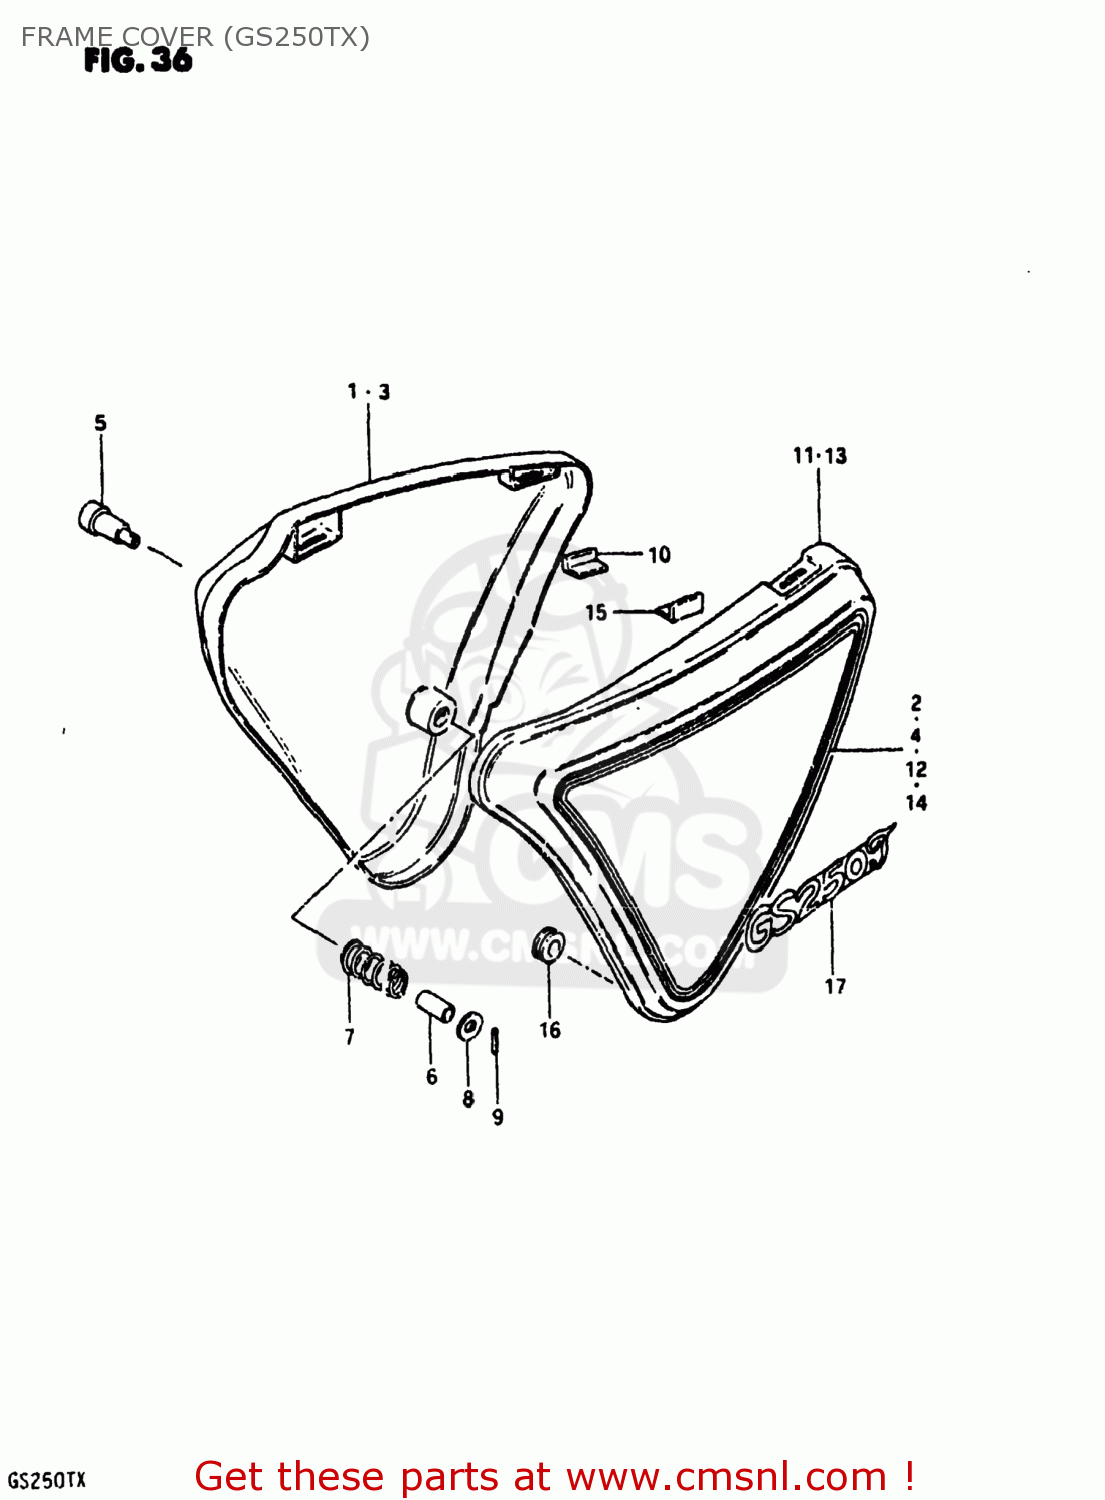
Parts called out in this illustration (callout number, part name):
1	COVER,FRAME,RIGHT
2	TAPE SET,FRAME COVER,RIGHT
3	COVER,FRAME,RIGHT
4	TAPE SET,FRAME COVER
5	KNOB, FRAME COVER RH
6	SPACER(14.9X17.3X13.5)
7	SPRING
8	WASHER (6.5X24X1.6)
9	PIN,SPRING(2.5X18)
10	CUSHION,FRAME COVER
11	COVER,FRAME,LEFT
12	TAPE SET,FRAME COVER
13	COVER,FRAME,LEFT
14	TAPE SET,FRAME COVER
15	CUSHION,FRAME COVER
16	CUSHION
17	EMBLEM,FRAME COVER
